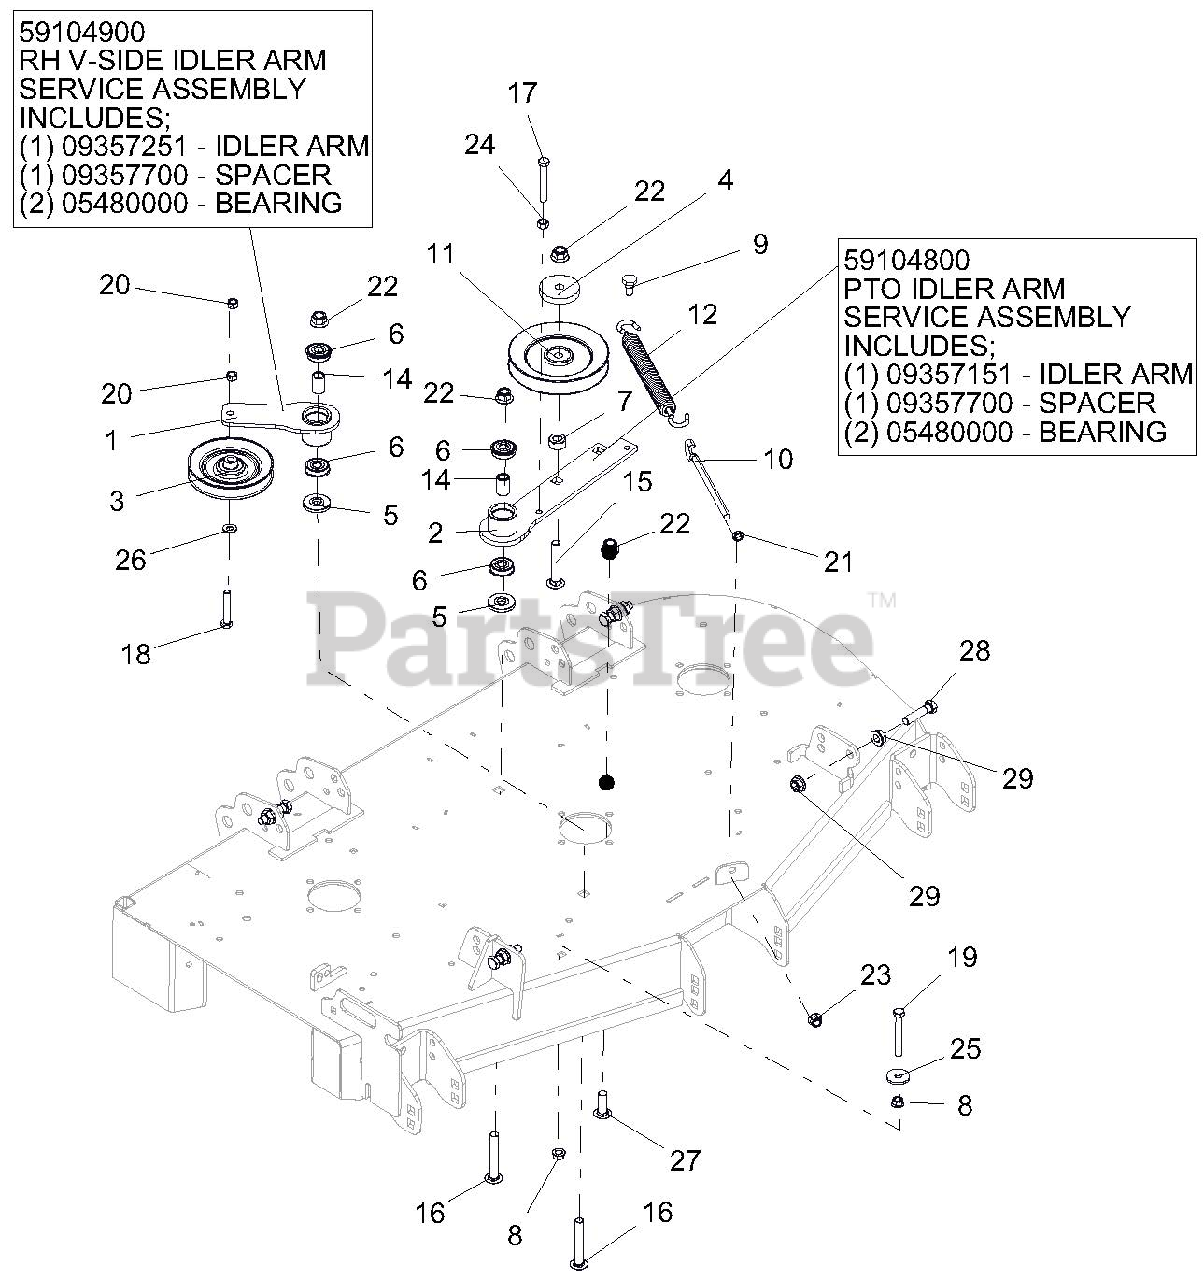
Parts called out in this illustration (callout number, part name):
1	WLDMT, DECK RH IDLER ARM-BLACK
1	RH V-SIDE IDLER ARM SERVICE ASSEMBLY
1	IDLER ARM
1	SPACER
1	BEARING
2	WLDMT, DECK PTO IDLER ARM-BLACK
2	PTO IDLER ARM SERVICE ASSEMBLY
2	IDLER ARM
2	SPACER
2	BEARING
3	IDLER, V-5.00" W/.69 STANDOFF
4	CAP, IDLER BEARING SEALING
5	SPACER, IDLER ARM
6	BRG, BALL .501 X 1.38 X .438 SEALED
7	BSHG, SPCR .502 X .997.50 PM
8	@NUT-SPNLK-FLG .375-16 YWZC
9	BLT, SHLDR EP .38-16X.30 HEX YZ
10	BOLT, .38-16X6.00 .62 DIA EYE
11	SHEAVE, .50" ID X 6.00" OD V-IDLER
12	SPRG, EXTENSION
14	SPACER, .510 X .750 X 1.148
15	BLT-RDHDSQNK .50-13X3.00 G5 Y
16	BLT-RDHDSQSHNK .50-13X3.25 YWZC
17	BLT-HEX .38-16X2.75 GR5 YWZC
18	BLT-HEX .38-16X2.25 GR5 YWZC
19	BLT-HEX .38-16X3.00 GR5 YWZC
20	NUT-LK-CTR .38-16 YWZC
21	NUT, JAM .375-16 YWZC
22	NUT-LK-NYL-FLG .50-13 YWZC
23	NUT-LK-NYL-FLG .38-16 YWZC
24	NUT-HEX .38-16 YWZC
25	WSHR-FL-STL .406X1.375X.135 YZ
26	WSHR-FL-STL.406X.812X.065 YWZ
27	BLT-RDHDSQSHNK .50-13X1.50 YWZC
28	BLT, HEX M12-1.75X50 CLS8.8 YZ
29	NUT, SPLK -FLG M12-1.75 YZ
